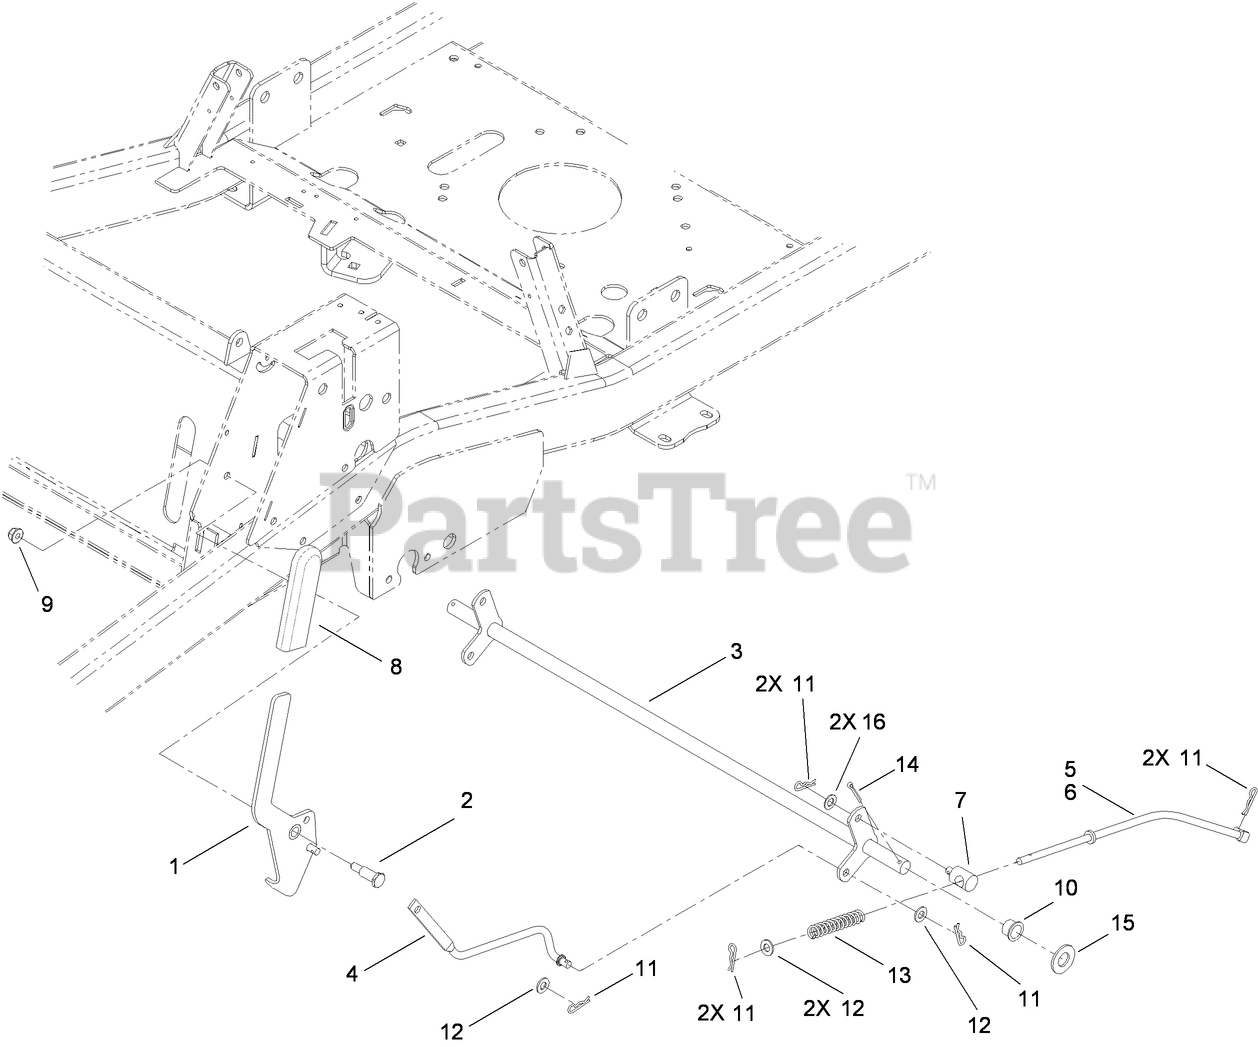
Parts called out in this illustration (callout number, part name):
1	HANDLE-BRAKE
2	SCREW-SHOULDER
3	BRAKE-BELLCRANK
4	LINK-BRAKE
5	ROD-BRAKE, LH
7	FITTING-ROD
8	GRIP-LEVER
9	NUT-HF, NI
10	BUSHING-FLANGE, NI
11	PIN-COTTER
12	WASHER-PLAIN
13	SPRING-RETURN, NEUTRAL
14	PIN-COTTER
15	WASHER-FLAT
16	WASHER
